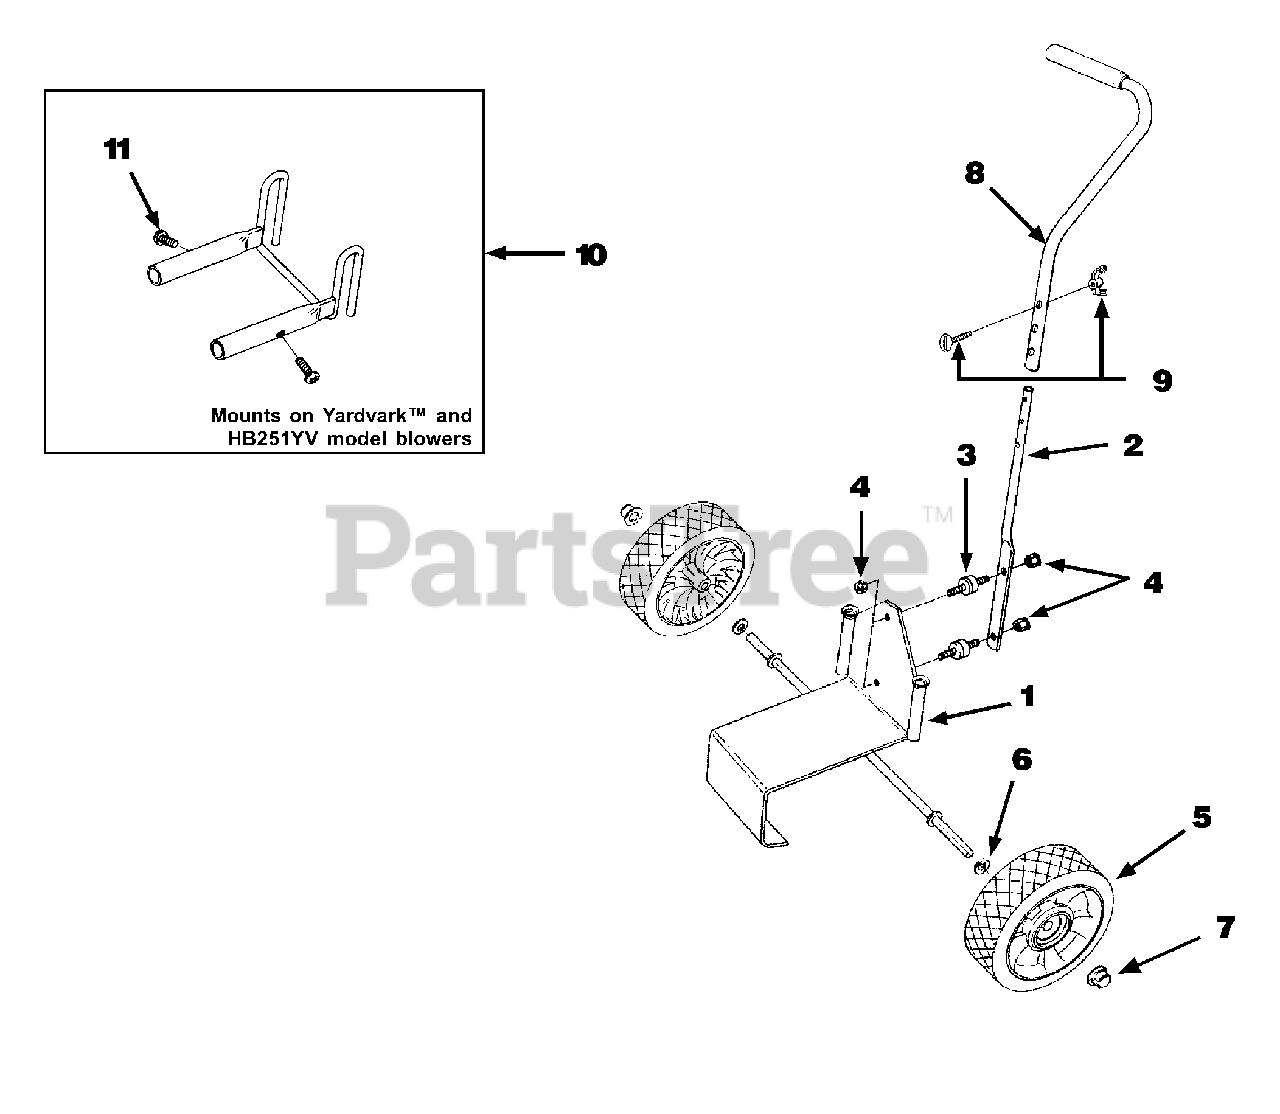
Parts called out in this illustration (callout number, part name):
1	DOLLY COMPLETE
2	HANDLE, Lower
3	ISOLATOR KIT (2 per)
4	NUT (1/4-20) (4 per)
5	WHEEL
6	WASHER
7	NUT, Push
8	HANDLE, Upper
9	SCREW & WING NUT
10	BRACKET
11	SCREW, Torx Hd. (8-32 x 1/2")
